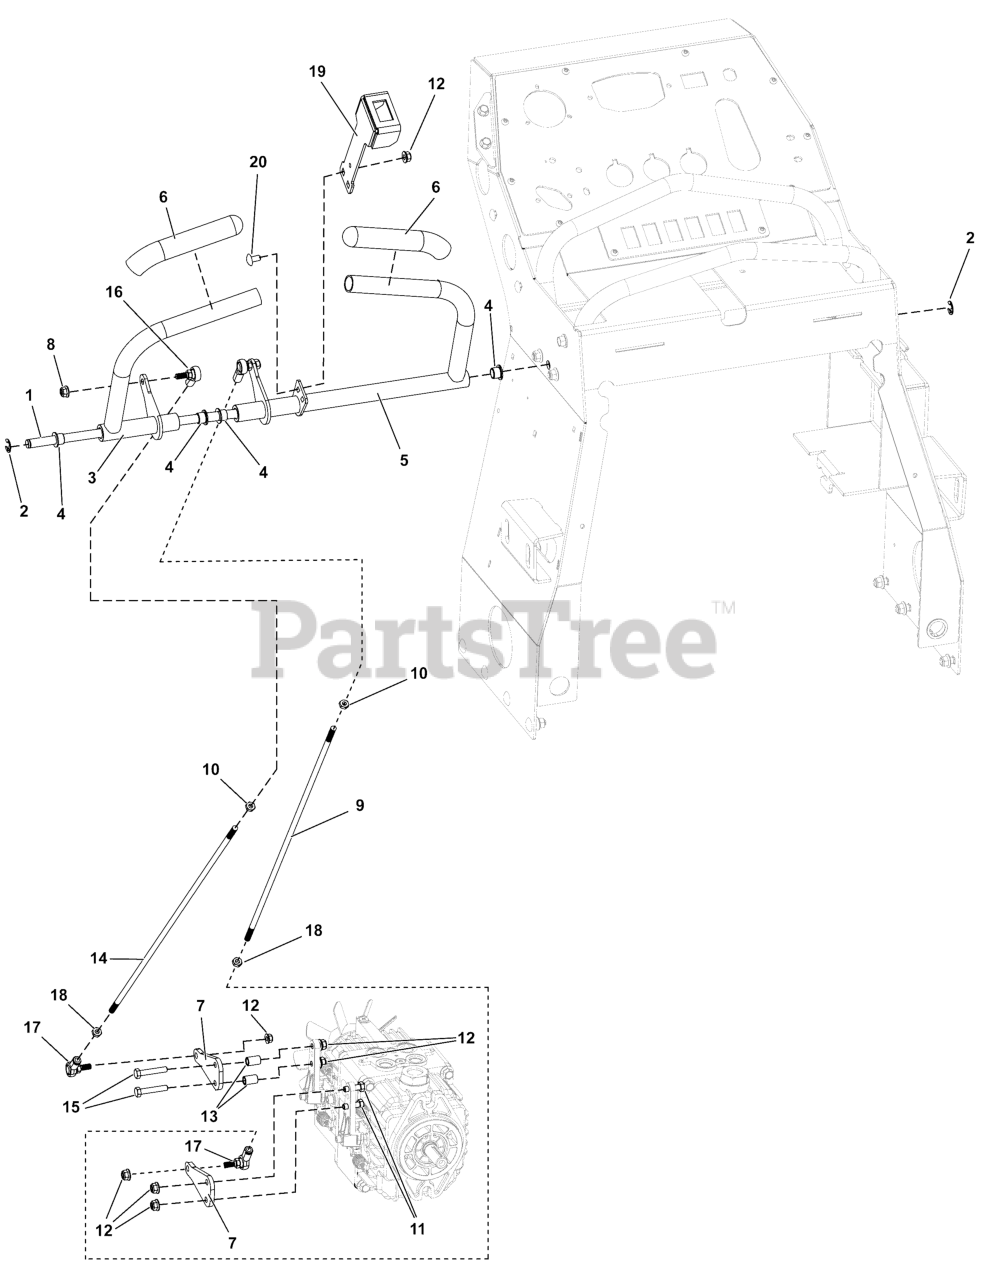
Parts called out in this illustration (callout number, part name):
1	SHAFT, STEERING LEVERS
2	E-RING, 0.500" SHAFT YZ
3	WELD, STEERING CONTROL LH
4	BSHG-FL, .500" X .625" X .500", .875"x .062" IR
5	WELD, STEERING CONTROL RH
6	GRIP, MOTION CONTROL
7	ARM, RTN PARKER SYM
8	NUT-HEX-NYLK, FLG .3125"-24 ZP
9	ROD, STEERING RH
10	NUT-HEX, JAM .3125"-24 SS188
11	SCR-CAP, HEX .3125"-18 X 1.000" SS188
12	NUT-HEX, JAM .3125"-24 LH SS188
13	SPCR-SS, 303 .343" X .500" X .779"
14	ROD, STEERING LH PARKER
15	SCR-CAP, HEX .3125"-18 X 1.750" SS188
16	BALL JOINT, 5/16-24 RH FEMALE W/STUD, BR
17	BALL JOINT, 5/16-24 LH FEMALE W/STUD, BR
18	NUT-HEX-NYLK, FLG .3125"-18 SS188
19	WELD, ROCKER SWITCH MOUNT BRACKET
20	BLT-RDHDSQNK, .3125"-18 X .750" SS188
